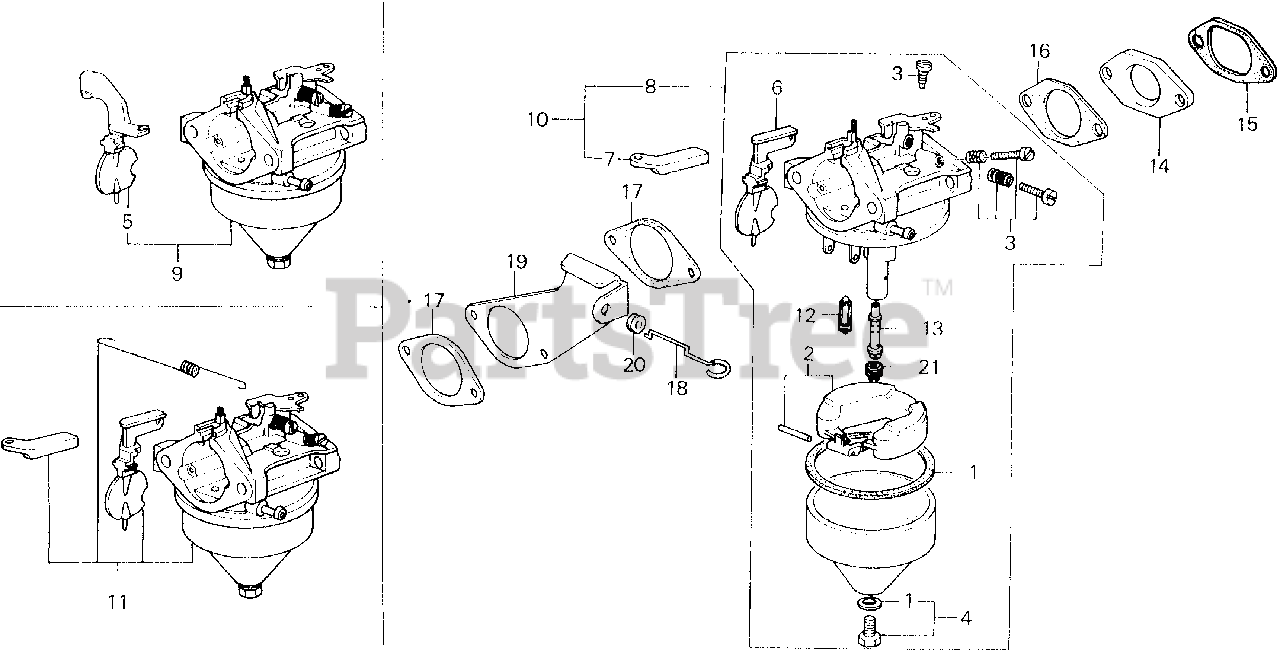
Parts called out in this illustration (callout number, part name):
1	GASKET SET
2	FLOAT SET
3	SCREW SET A
4	SCREW SET B
5	CHOKE SET (NOT AVAILABLE)
6	CHOKE SET
7	ARM, CHOKE LEVER
8	CARBURETOR ASSY.
8	CARBURETOR ASSY. (BB28A D)
9	CARBURETOR ASSY.
9	CARBURETOR ASSY. (BB28A A)
10	CARBURETOR ASSY.
11	CARBURETOR ASSY.
12	VALVE, FLOAT
13	NOZZLE, MAIN
14	INSULATOR, CARBURETOR
15	GASKET, INSULATOR
16	GASKET, CARBURETOR
17	GASKET, AIR CLEANER
18	ROD, CHOKE CONTROL
19	STAY, CHOKE CONTROL
20	GROMMET, CHOKE ROD
21	JET, MAIN (#62)
